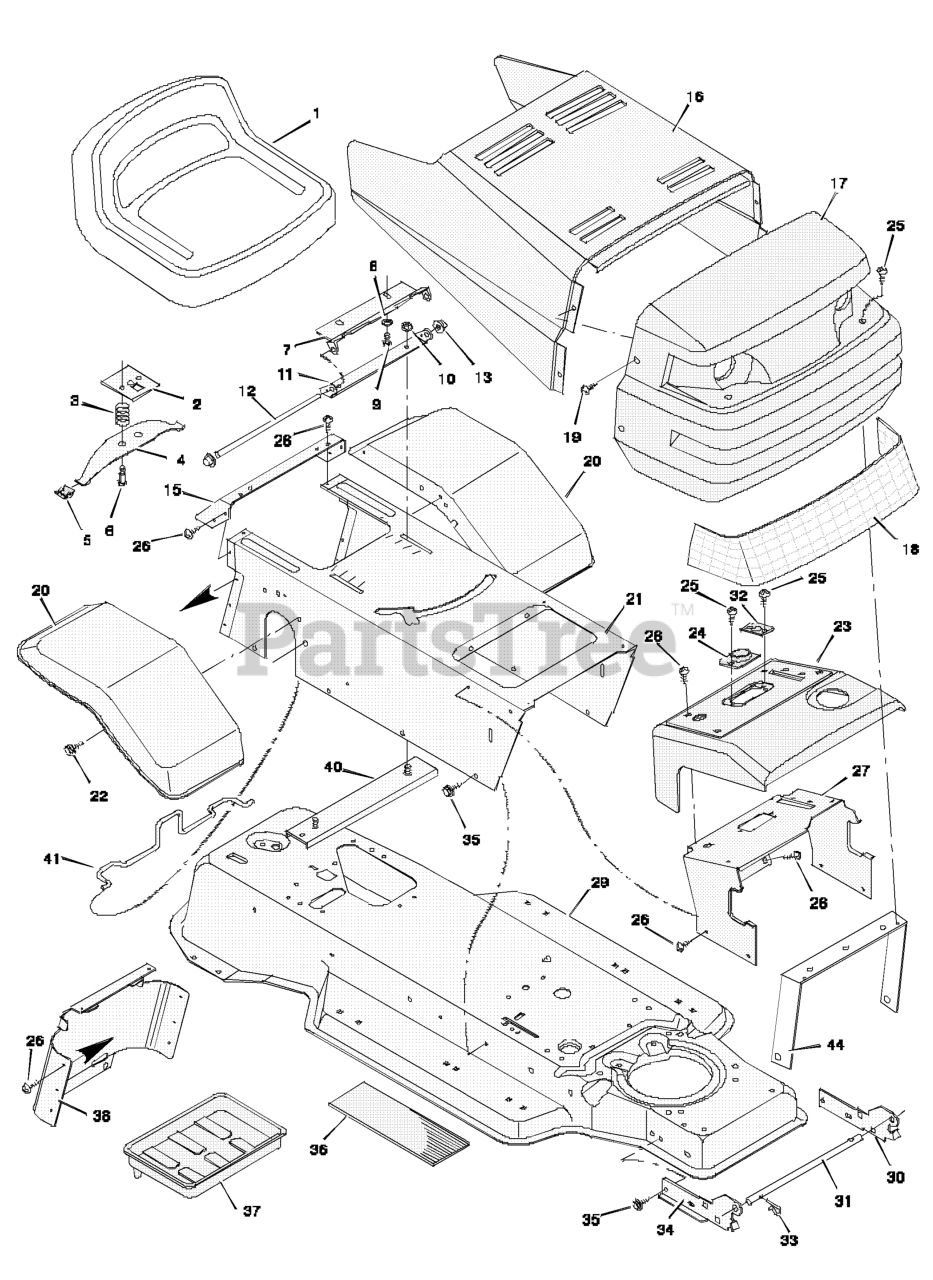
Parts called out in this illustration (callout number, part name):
2	Plate Assembly, Switch
3	Spring, Compression
4	Spring, Seat
5	Glide, Spring
6	Bolt, Shoulder
7	Support, Seat
8	Lockwasher
9	Bolt, Hex
10	Locknut, Flange
11	Bracket, Pivot
12	Rod, Pivot
13	Cap, Push On
15	Fender, Apron
17	Grille Assembly
21	Console Assembly
23	Dash Panel
24	Bearing, Steering
26	Screw
27	Support, Dash
29	Frame Assembly
30	Bracket, Left Grille
31	Rod, Pivot
32	Bearing
33	Pin, Hair
34	Bracket, Right Grille
37	Tray, Battery
38	Cap, Console
39	Bolt
40	Channel Assembly
41	Clamp, Battery
44	Brace, Grille
